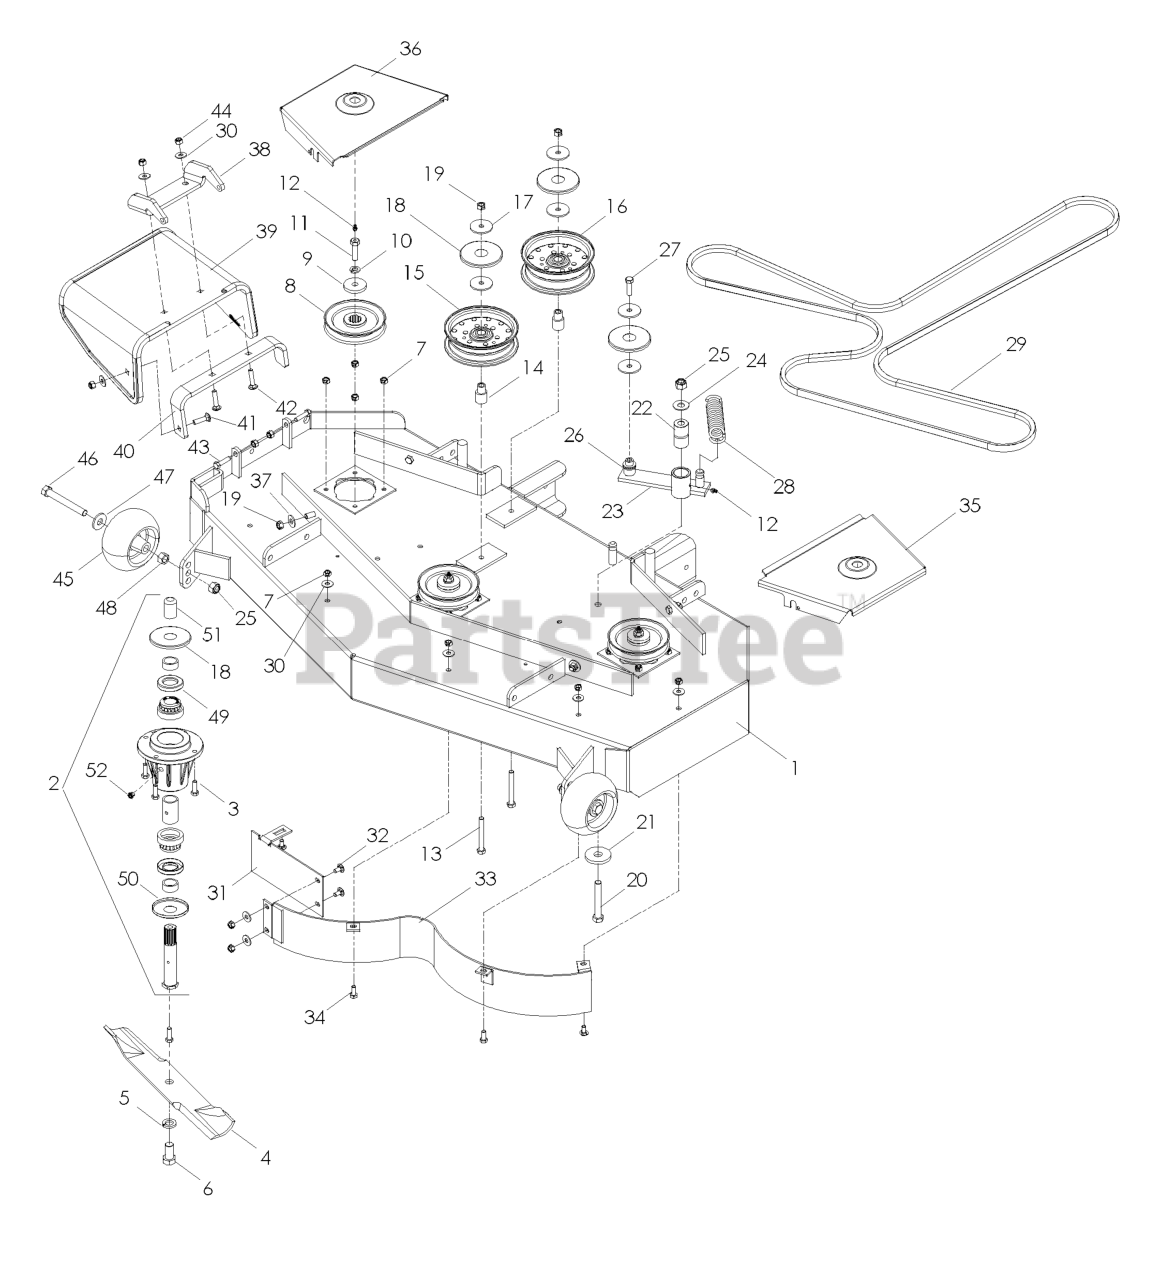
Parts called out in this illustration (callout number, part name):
1	DECK W/DECALS 48"
2	HOUSING ASM, 52/61
3	HCS 5/16C X 1
4	BLADE OEM 16 1/4"
5	LOCKWASHER 5/8
6	HCS 5/8F X 1 1/4
7	NUT 5/16C CENTERLOCK
8	PULLEY 42-48
9	SPINDLE WASHER
10	WASHER 7/16 LOCK
11	HCS 7/16-20 GD 8 SPEC
12	ZERK
13	HCS 3/8C X 3
14	IDLER BUSHING
15	IDLER PULLEY
16	IDLER PULLEY (TALL)
17	WASHER, 3/8 SPEC
18	TOP DUST CAP
19	NUT 3/8C CENTERBLOCK
20	HCS 1/2C X 3 1/4
21	WASHER, SUPPORT
22	PIVOT BUSHING
24	WASHER 1/2 FLAT
25	NUT 1/2-13 HEX NYLOC ZD
26	BUSHING
27	HCS 3/8C X 1 1/4 GR5
29	BELT, DECK
30	WASHER 5/16 FLAT
31	CENTER BAFFLE 48"
32	CARRIAGE BOLT 5/16C X 5/8"
33	MAIN BAFFLE - 48" DECK BLK
34	HCS 5/16C X 3/4
35	LT 48 SHIELD, ORG
36	RT 48 SHIELD, ORG
37	WASHER 3/8 FLAT
38	PIVOT BRACKET - CHUTE
39	CHUTE, RUBBER DISCHARGE WB
40	BRKT, REINF-CHUTE WB
41	BOLT, CARRIAGE 5/16X1-1/4
42	RHSNB 5/16-18 X 1-1/2 GR 5 ZD
43	HCS 5/16C X 1 1/4
44	NUT 5/16 NYLOC
45	GAUGE WHEEL
46	HCS 1/2-13 X 4 GR 5 ZD
47	WASH USS FLAT 1/2
48	NUT HEX 1/2
49	SHAFT SEAL
50	BOTTOM DUST CAP
52	PLUG-VENTED
